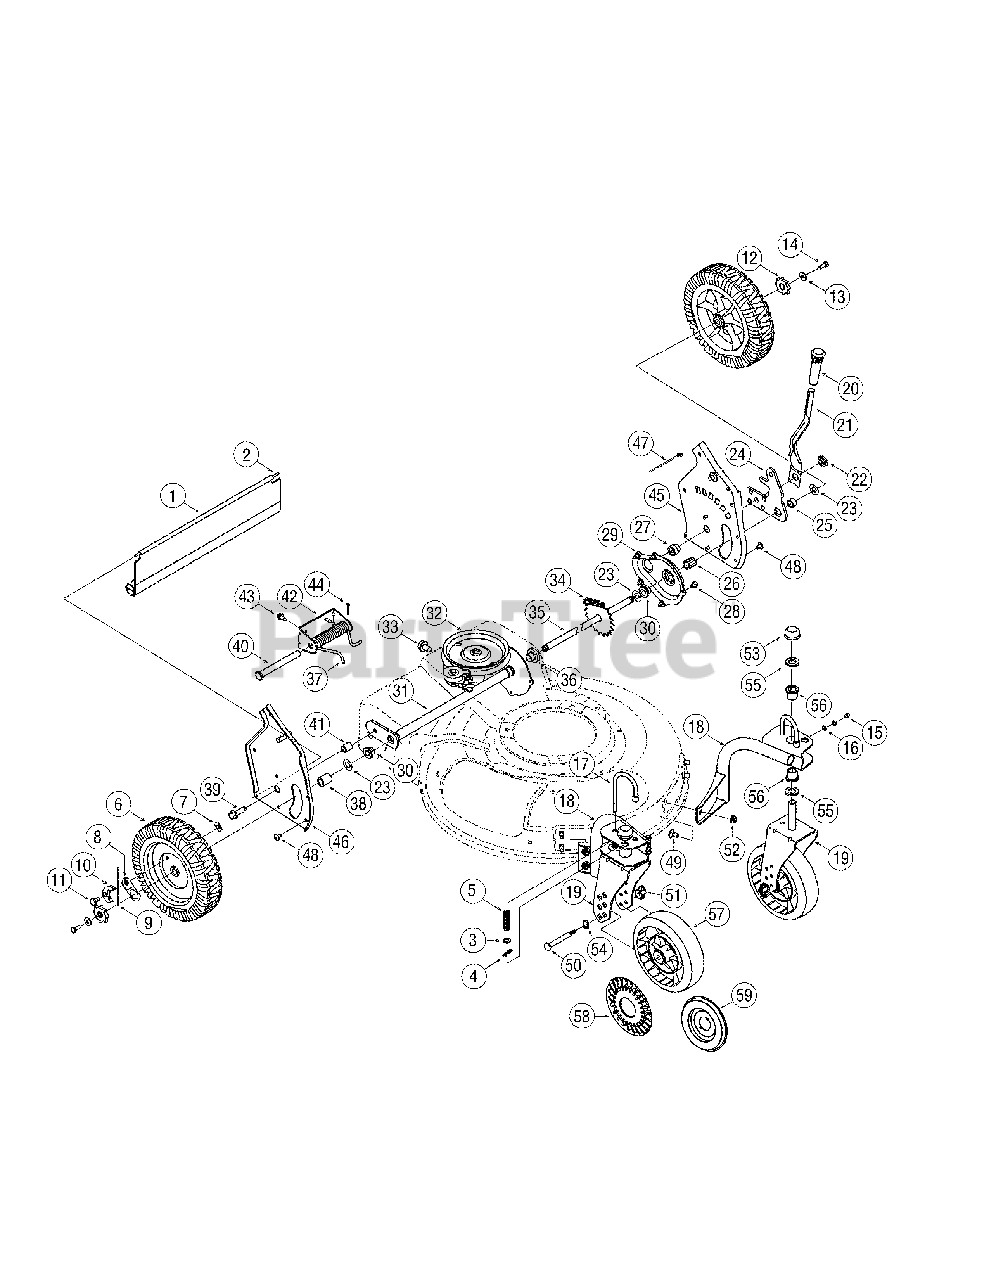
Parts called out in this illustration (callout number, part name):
1	Trail Shield
2	Trail Shield Wire
3	Flat Washer.330 ID x.630 OD
4	Cotter Pin
5	Compression Spring
6	Rear Wheel, 9 x 2.125
7	Top Lock Tab Weld Nut 1/4-20
8	Ratchet Pawl Plate
9	Plastic Spring Ratchet
10	Pawl RH
10	Pawl LH
11	Shoulder Screw.340 ID x.285 OD
12	Wheel Ratchet
13	Bell Washer.265 ID x.75 OD
14	Hex Cap Screw 1/4-20 x.620
15	Grease Fitting
16	Flat Washer.203 ID x.403 OD
17	Wheel Pin Lock
21	Spring Lever
22	Shoulder Nut.825 x .165 Lg.
23	Flat Washer .508 ID x 1.0 OD
24	Pivot Arm Assembly
25	Spacer .510 ID x .70 OD
26	Sleeve Bearing .504 ID x .830 OD
27	Shoulder Spacer
28	Tap Screw 1/4-20 x .375
29	Chain Cover Assembly
30	Flange Bearing .506 ID x .590 Lg
31	Transmission Axle Assembly
32	Transmission Assembly Complete
33	Hex Screw 5/16-18
34	Chain
35	Rear Axle Assembly
36	Flange Bearing .506 ID x .715 Lg
37	Torsion Spring
38	Spacer .550 ID x .750 OD
39	Screw 3/8-16 x .25
40	Clevis Pin .50 Dia x 4.82 Lg.
41	Spacer .385 ID x .624 OD
42	Spring Bracket: Height Adjustment
43	Screw 1/4-14 x .825
44	Cotter Pin
48	Screw 1/4-14 x.500
49	Carriage Bolt 5/16-18 x.62
50	Caster Axle
51	Wing Nut
52	Flange Lock Nut 5/16-18
53	Push Cap
54	Wave Washer.531 ID x.781 OD
55	Flat Washer.640 ID x 1.12 OD
56	Flange Bearing
57	Front Wheel, 7 x 2
58	Hubcap - Spoke w/ Hole
59	Hubcap - Radial Spoke
